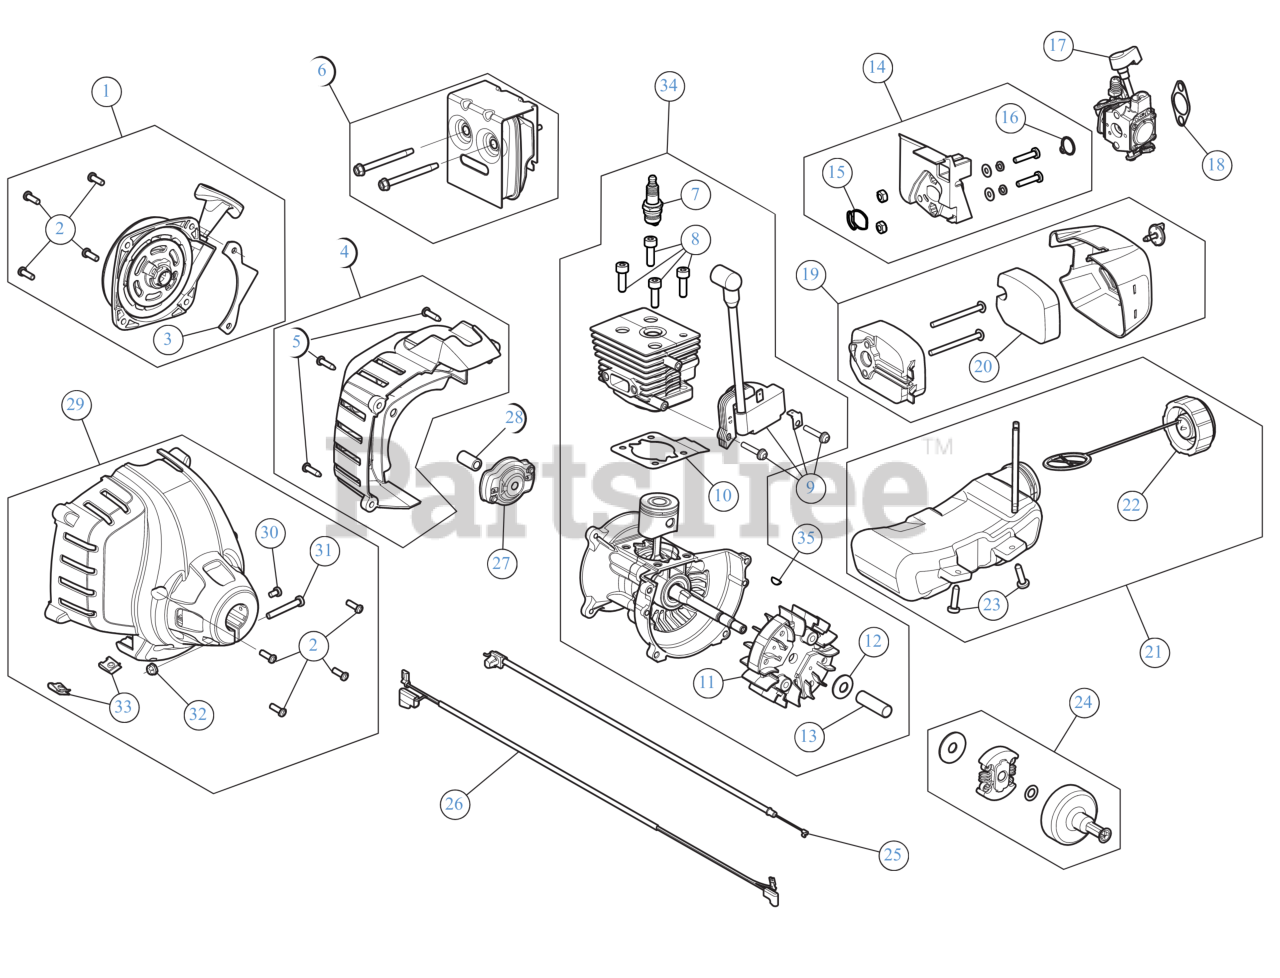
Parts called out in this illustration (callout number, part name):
1	STARTER ASSEMBLY RR
2	SCREW:10-32X.562:#8P
3	STARTER GUARD
4	REAR ENGINE COVER
5	SCREW, #8-16X.750 PH
6	MUFFLER ASSEMBLY
7	SPARK PLUG
8	SCREW 1/4 x 20 x .8125
9	MODULE MA-103
10	GASKET CYL
11	FLYWHEEL ASSEMBLY 27CC
12	BELL WASHER
13	SPACER
14	INTAKE ASSEMBLY
15	O-RING
16	O-RING
17	CARBURETOR
18	GASKET CARB
19	AIRCLEANER ASSEMBLY
20	AIR FILTER
21	FUEL TANK ASSEMBLY
22	FUEL CAP ASSEMBLY
23	SCREW:10-6 x .75
24	SMALL CLUTCH ASSEMBLY W/SMALL DRUM
25	THROTTLE CABLE
26	LEAD WIRES
27	PAWL ASSEMBLY AC5
28	ELECTRIC START ADP
29	CLUTCH COVER ASSEMBLY
30	SCREW, 8-32 x .312 P
31	SCREW
32	HEX NUT
33	NUT, TINNERMAN U-T
34	SHORT BLOCK 27CC
35	WOODRUFF KEY #403-.125 x .375
